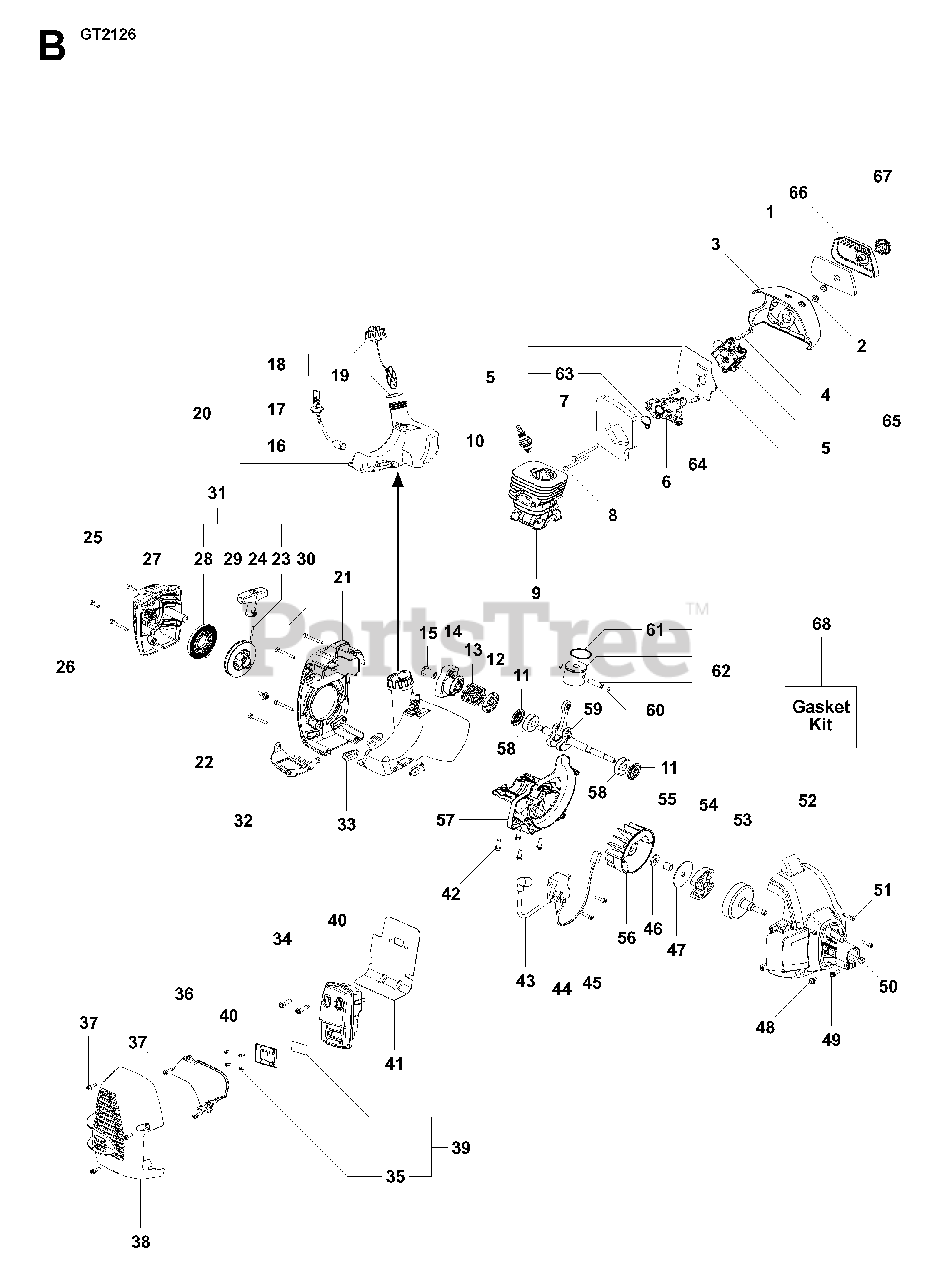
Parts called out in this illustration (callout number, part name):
1	FILTER AIRBOX
4	CHOKE LEVER
5	KIT GASKET CARB
6	CARB ADAPTOR
7	KIT GASKET 28CC TRIMMER
8	BOLT CARB ADAPTOR
9	CYLINDER
11	KIT SEAL CRANKSHAFT
12	WASHER STARTER
13	SPRING STARTER CUP
14	ASSY-STARTER CUP
15	COUPLING STARTER
16	FUEL PICK-UP ASSY
17	KIT FUEL LINE
18	ASSY - FUEL CAP W/RETAINER
19	O RING NITRILE
21	SHROUD REAR
25	SCREW M5-0.8X30MM
26	SCREW M4 X 1.75 PT 16MM
28	%KIT STARTER SPRING
29	KIT STARTER PULLEY
32	PLATE WEAR
33	ISOLATOR FUEL TANK
34	BOLT MUFFLER
35	SCREW-10-16 X 1/2 HI-LO
36	SHIELD HEAT
37	SCREW M4 X 1.75 PT 16MM
39	KIT SPARK ARRESTOR SCREEN
41	GASKET PAPER METAL
42	B0LT, C/SHAFT 36/41
43	IGNITION MODULE
44	ASSY MODULE LEAD WIRE
45	SCREW M4 X .70 TT 16MM
47	WASHER-CLUTCH
50	NUT HEX LOCK 10-24
51	SCREW M4 X .70 TT 16MM
53	ASSY-CLUTCH DRUM
54	%KIT CLUTCH ASSY
55	SPACER FLYWHEEL
57	CRANKCASE CASTING
58	BEARING RADIAL BALL (6201)
59	KIT CRANKSHAFT ASSY
60	WRIST PIN RET.
61	RING PISTON
62	KIT PISTON 28CC TRIMMER
63	KIT GASKET 28CC TRIMMER
64	B0LT, C/SHAFT 36/41
66	COVER AIR BOX
67	ASSY - AIR BOX KNOB
68	KIT GASKET 28CC TRIMMER
